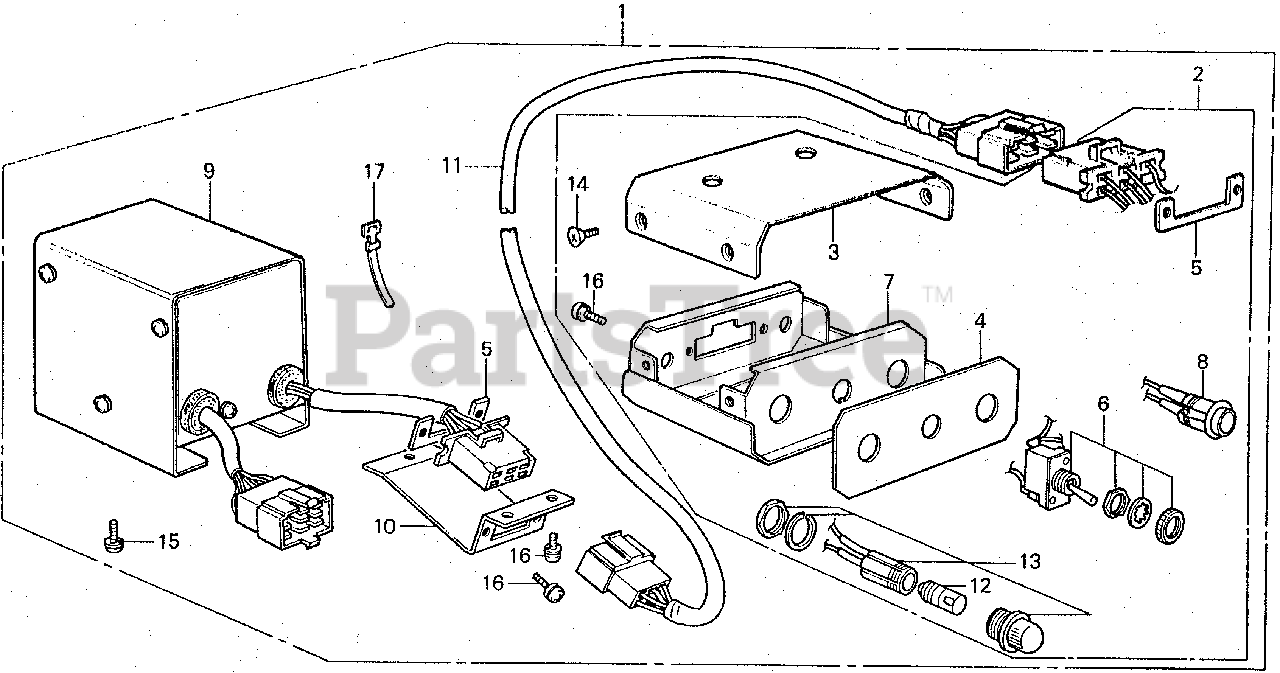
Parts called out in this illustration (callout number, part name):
1	CONTROL KIT, REMOTE
2	BOX ASSY., SWITCH
3	COVER (UPPER)
4	PANEL, FR.
5	PLATE, CONNECTOR SETTING
6	SWITCH, TOGGLE
7	CASE, SWITCH
8	SWITCH, PUSH
9	BOX ASSY., RELAY
10	HOLDER, CONNECTOR
11	CABLE, REMOTE CONTROL
12	BULB, DASH (24V-2W)
13	SOCKET ASSY., PILOT LAMP
14	SCREW, FLAT (4X8)
15	SCREW-WASHER (5X12)
16	SCREW-WASHER (4X12)
17	BAND B1, WIRE
